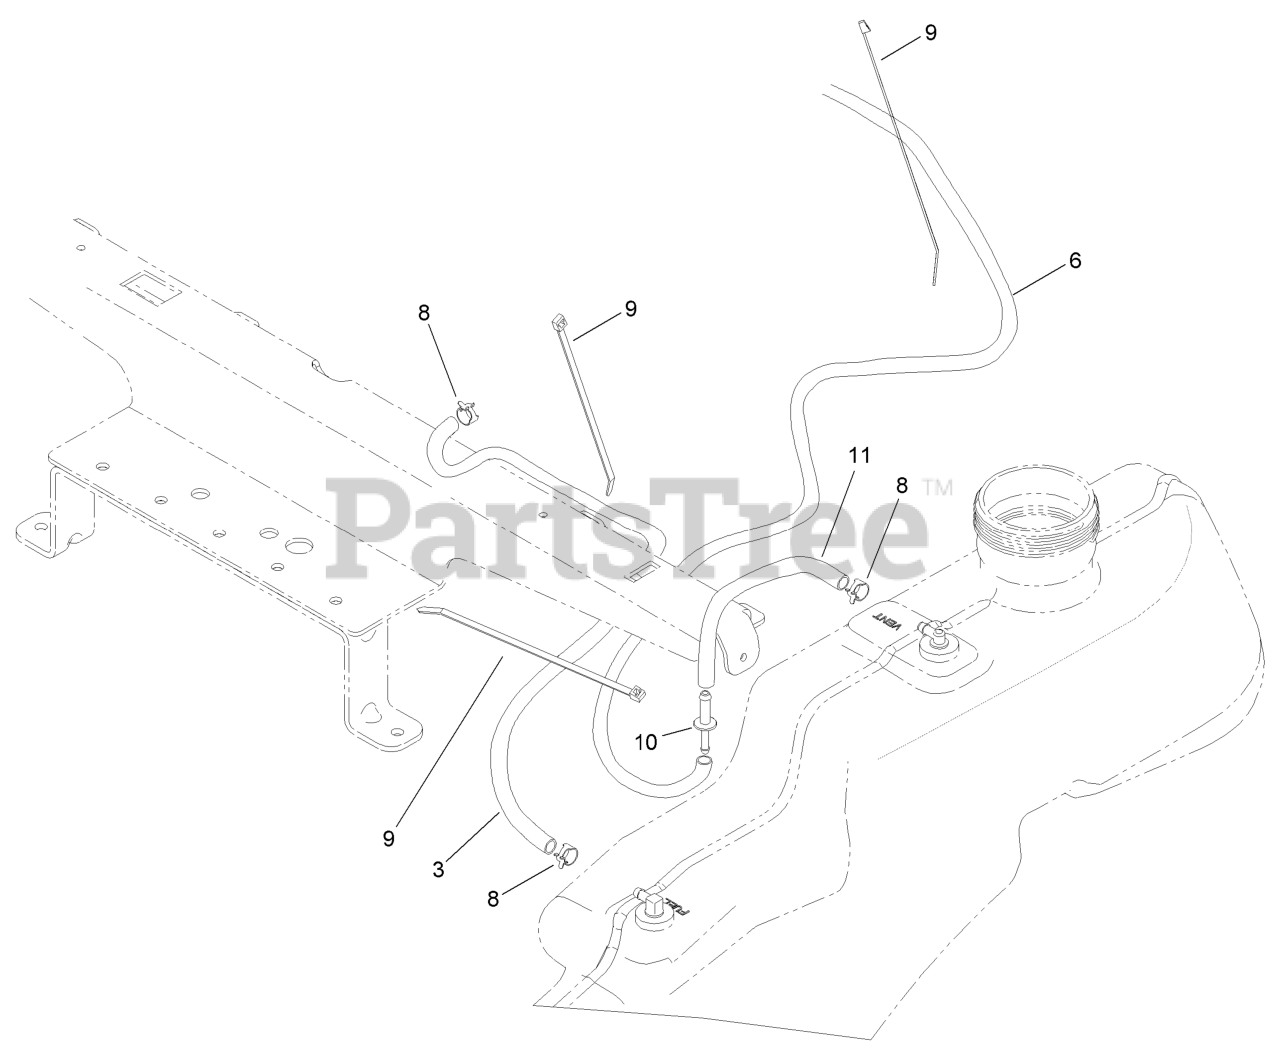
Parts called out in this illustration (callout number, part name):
3	HOSE-FUEL
6	HOSE-FUEL
8	CLAMP-HOSE
9	TIE-CABLE
10	ADAPTOR-ORIFICE
11	HOSE-FUEL
